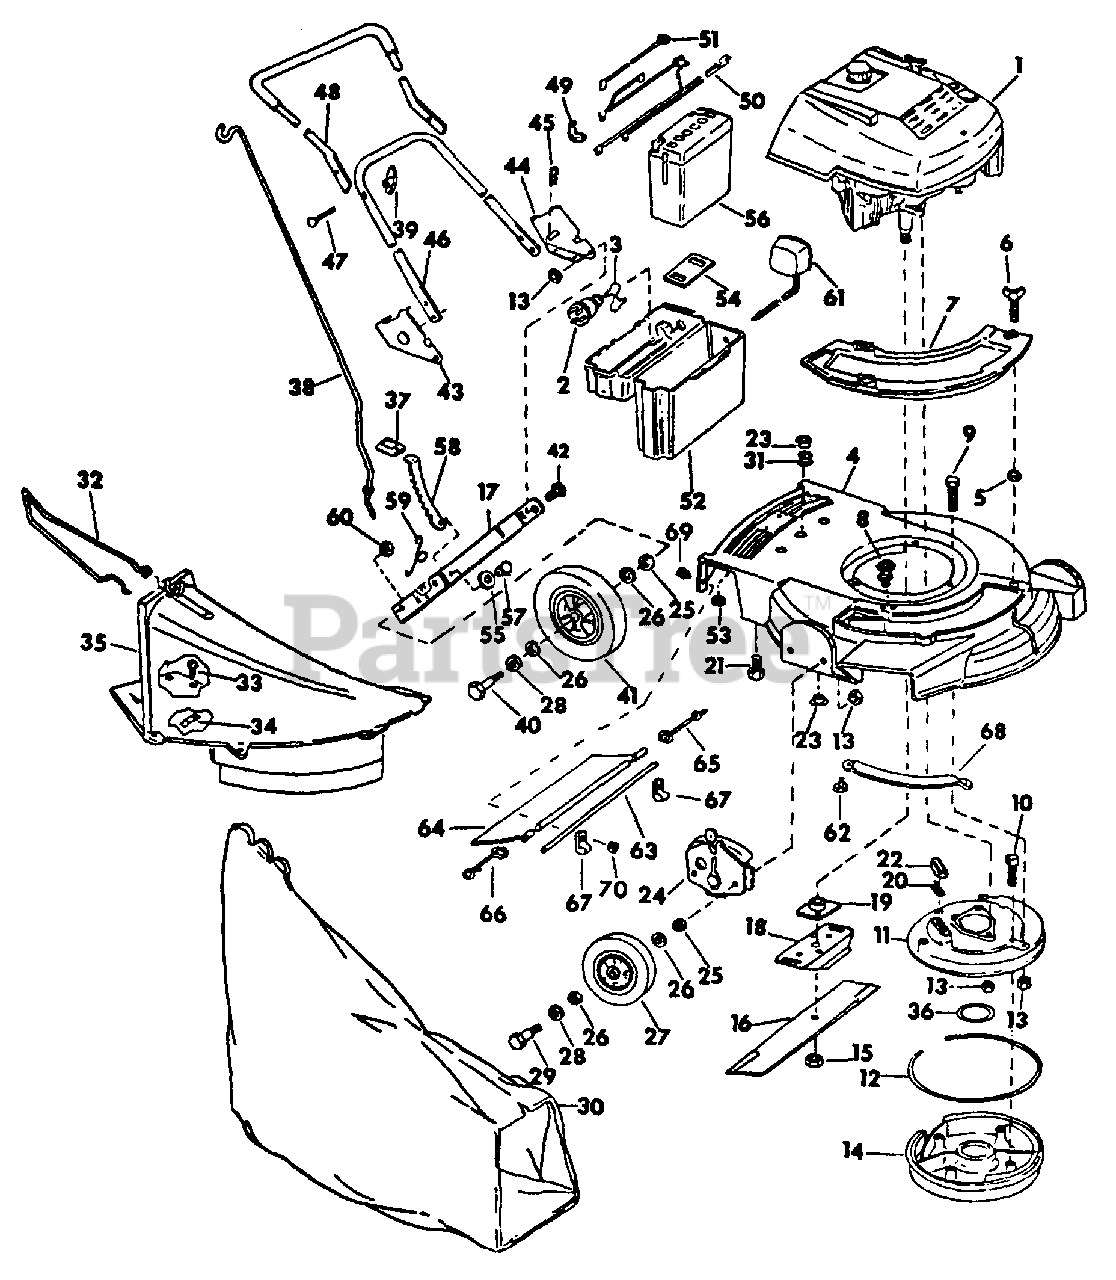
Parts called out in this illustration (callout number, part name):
1	ENGINE, IH
4	HOUSING ASSY, 21IN.
6	SCREW, WING
7	COVER, CHUTE OPENING
8	SCREW, SHOULDER
9	SCREW, MUFFLER PLT TO HSG
10	SCREW, MUFFLER TO PLATE
11	PLATE, MUFFLER
12	GASKET, MUFFLER OUTSIDE
14	COVER, MUFFLER
16	BLADE, 21 in.
18	STIFFENER, BLADE
19	COLLAR & PLATE
20	GASKET, EXHAUST
21	SCREW, HANDLE BRACKET
22	SLEEVE, EXHAUST GASKET
23	SPACER, FLANGED
24	ADJUSTMENT, HEIGHT
26	WASHER, FELT
27	WHEEL AND TIRE - 6 IN. FRONT
28	WASHER, WHEEL BOLT HD
29	BOLT, WHEEL FRT SHOULDER
32	GUARD, WHEEL
35	CHUTE ASSY
36	GASKET, MUFFLER INSIDE
38	ROD, GRASS BAG
40	BOLT, REAR WHEEL
41	WHEEL & TIRE - 8 IN. REAR
43	BRACKET L PIN, RH
44	BRACKET L PIN, LH
46	HANDLE, BOTTOM
48	HANDLE & GRIP, TOP
49	POD, INSULATION
52	BOX, BATTERY
53	WASHER, BATTERY MTG BRACKET
54	STRAP, BATTERY BOX MTG
55	WASHER, SPRING
56	BATTERY, DRY CHARGED
57	PIN, HEIGHT ADJ LEVER
58	LEVER, REAR HGT ADJ
61	CHARGER, TRICKLE
65	SPRING, SHIELD LH
66	SPRING, SHIELD RH
68	BAR, TOE - 21IN.
69	SCREW, 1/4-20 X 5/8 ZND HEX-HD CAP
70	NUT, 1/4-20 HEX LOCK CAD.
